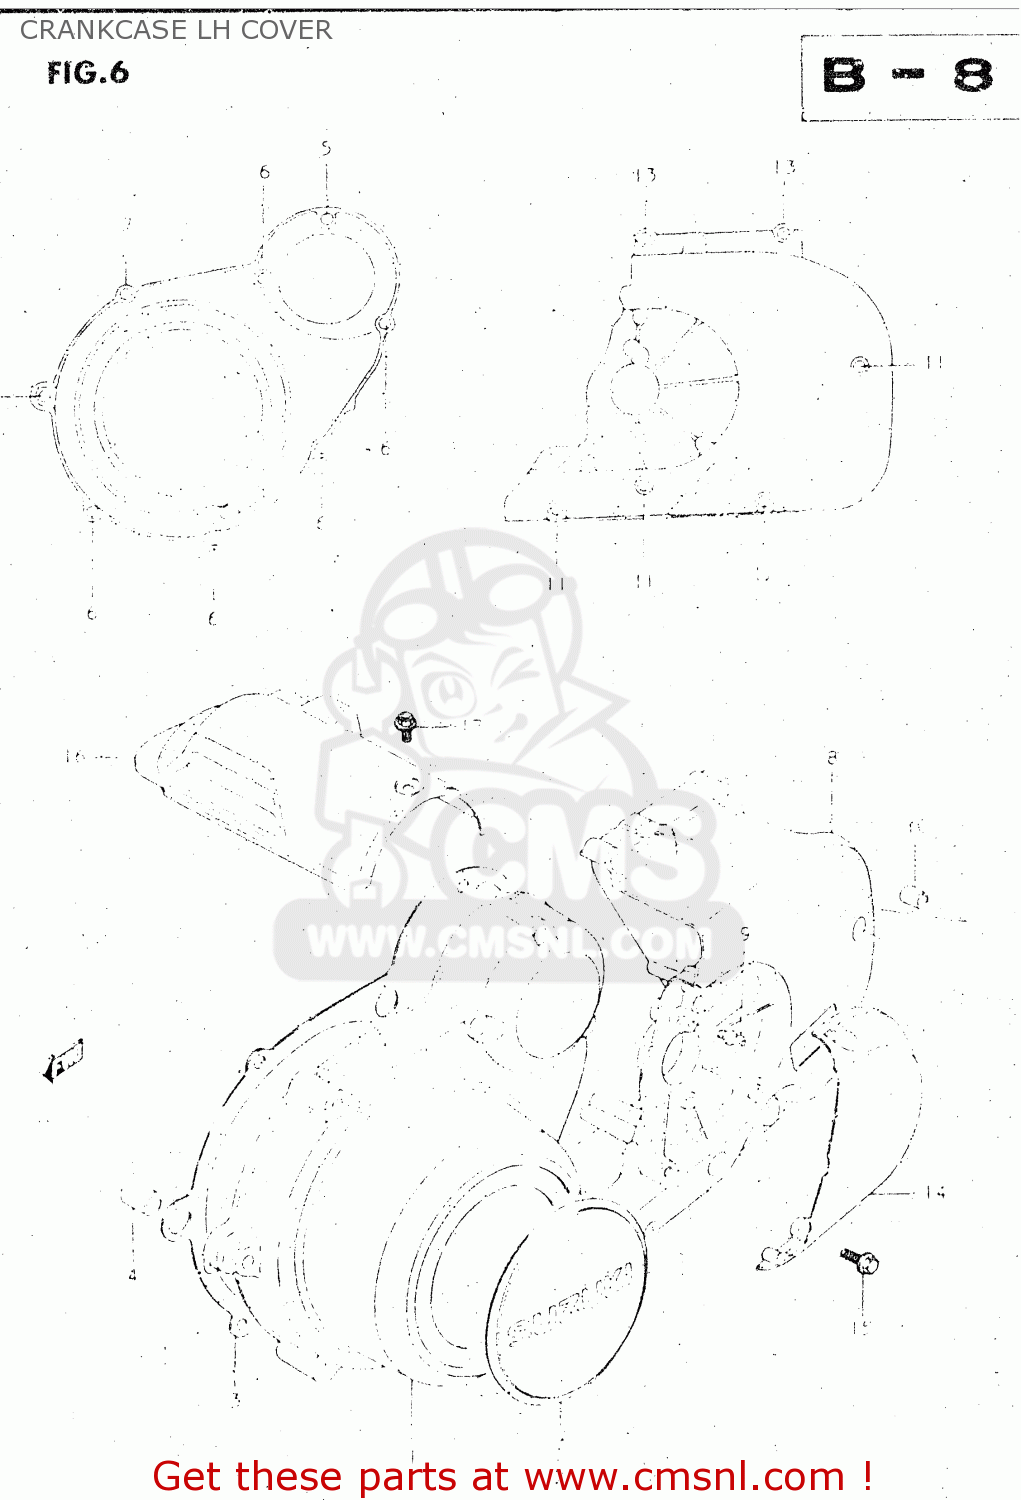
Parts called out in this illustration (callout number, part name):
1	COVER,MAGNETO
2	EMBLEM,MAGNETO COVER
3	GASKET,MAGNETO COVER (MCA)
4	PIN
5	BOLT
6	BOLT (6X40)
7	BOLT (6X35)
8	COVER SET,ENGINE SPROCKET
9	NIPPLE
10	PIN
11	BOLT
12	BOLT
13	BOLT (6X30)
14	CAP,CLUTCH RELEASE ADJUST
15	BOLT 5X16
16	COVER,STARTER MOTOR
17	BOLT
